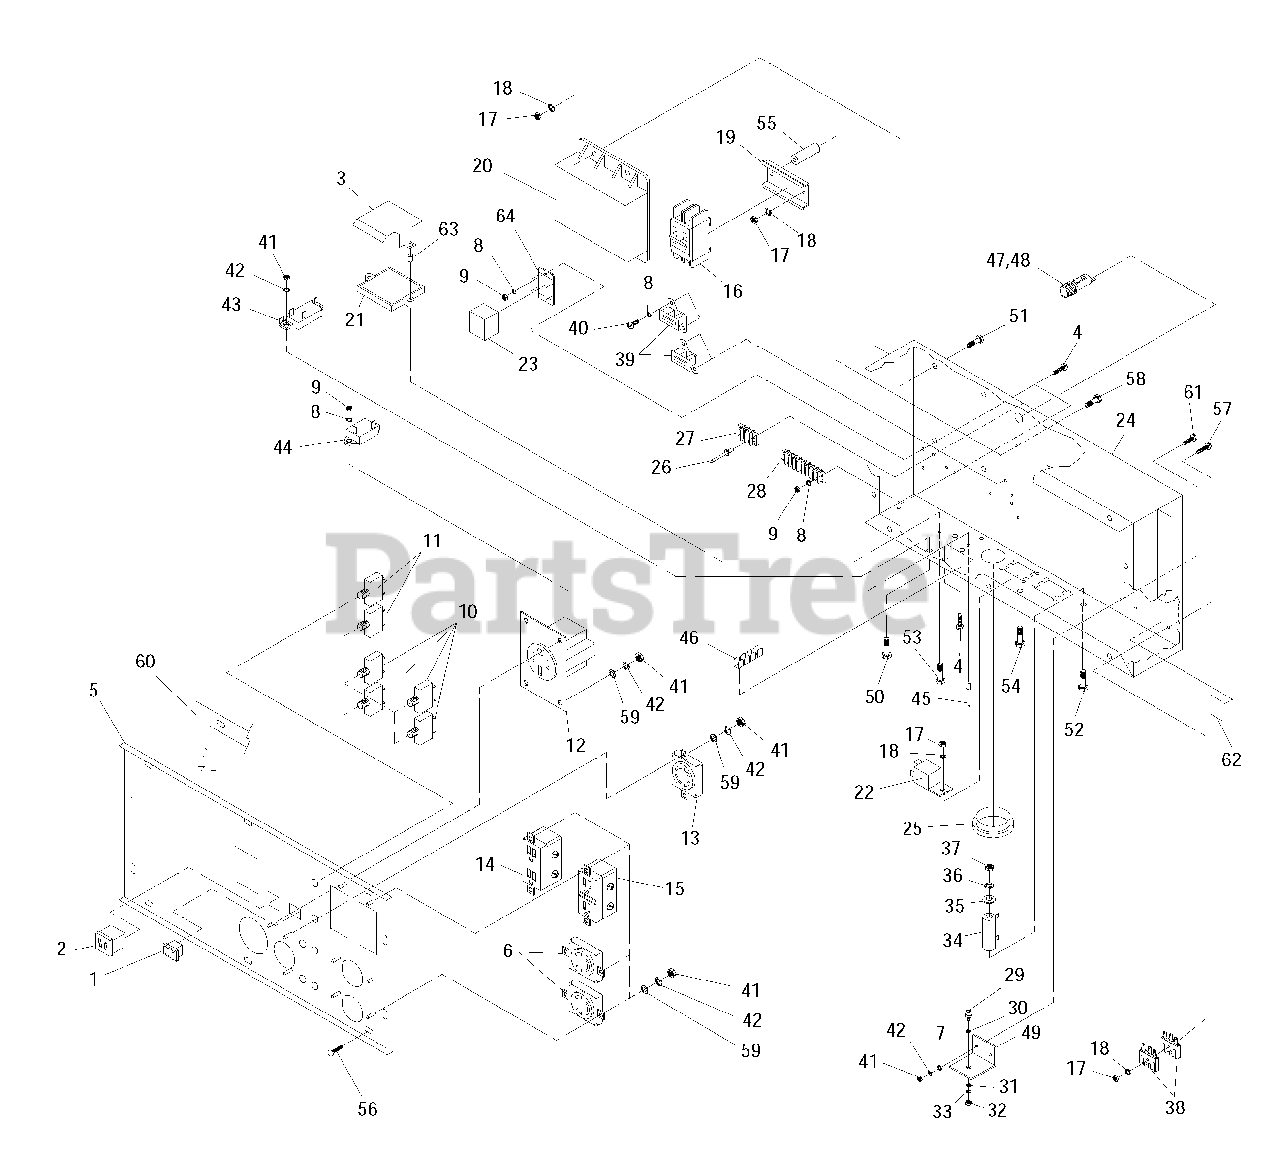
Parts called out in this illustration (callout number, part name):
1	SWITCH, ROCKER -/0
2	OUTLET, 12VDC SNAP
3	COVER, GOVERNOR CONTROL
4	SCREW PPHM M3-0.5 X 12
5	PANEL, SHEET METAL
6	OUTLET 30A 120V RECEPT
7	WASHER FLAT #6
8	WASHER LOCK M3
9	NUT HEX M3-0.5 G8
10	CIRCUIT BREAKER 30A
11	CIRCUIT BREAKER 20A
12	OUTLET 50A 125/250V
13	OUTLET 30A 125/250V
14	OUTLET 20A 120V DPLX
15	OUTLET 20A 120V GFCI
16	CIRCUIT BREAKER 50A 400V 2POLE
17	NUT HEX M5-0.8 G8
18	WASHER LOCK #10
19	DIN RAIL 59.5mm LONG
20	ASSEMBLY VOLTAGE REGULATOR 60HZ
21	ELECTRONIC GOVERNOR / IDLE CONTROLLER
22	RELAY PNL 12VDC SPST 30A
23	RELAY 3PDT 12VDC
24	CONTROL PANEL BOX
25	BUSHING SNAP
26	RIVET POP .156 X .160-.164 / #20
27	BLOCK TERMINAL 20A 2 X 6 X 1100V
28	BLOCK DOUBLE ROW TERMINAL 8 POSITION
29	RECTIFIER MSC 12A 600V
30	WASHER MICA .203
31	WASHER STEP NYLON .20
32	NUT HEX #10-32
33	WASHER FLAT #10
34	RESISTOR 25R 5% 25W
35	WASHER FLAT 1/4
36	WASHER LOCK M6-1/4
37	NUT HEX M6-1.0 G8
38	RECTIFIER-BATTERY CHARGER
39	TRANSFORMER, IDLE CURRENT
40	SCREW PPHM M3-0.5 X 8
41	NUT HEX M4-0.7 G8
42	WASHER LOCK M4
43	CIRCUIT BREAKER 6 X 1
44	CIRCUIT BREAKER 10 X 1 12VDC 1/4"QC
45	RIVET POP .125 X .129-.133 / #30
46	LUG GRND 8 TABS
47	HOLDER FUSE
48	FUSE 10A X AGC10
49	HEATSINK
50	SCREW PPHM M4-0.7 X 10
51	SCREW HHC M5-0.8 X 16 G8.8
52	SCREW HHC M6-1.0 X 65 G8.8
53	SCREW HHC M5-0.8 X 25 G8.8
54	SCREW HHC M5-0.8 X 10 G8.8
55	SPACER .25 X .50 X 1.5
56	SCREW HHTT M5-0.8 X 10
57	SCREW PPHM M5-0.8 X 30
58	SCREW PPHM M5-0.8 X 50
59	WASHER FLAT #8
60	GASKET, PORTABLE CONTROL PANEL
61	SCREW PPHM M4-0.7 X 16
62	TAPE ELEC UL PERMACEL
63	NUT TRIC M5-0.8
64	RELAY BASE 3PDT 12VDC
